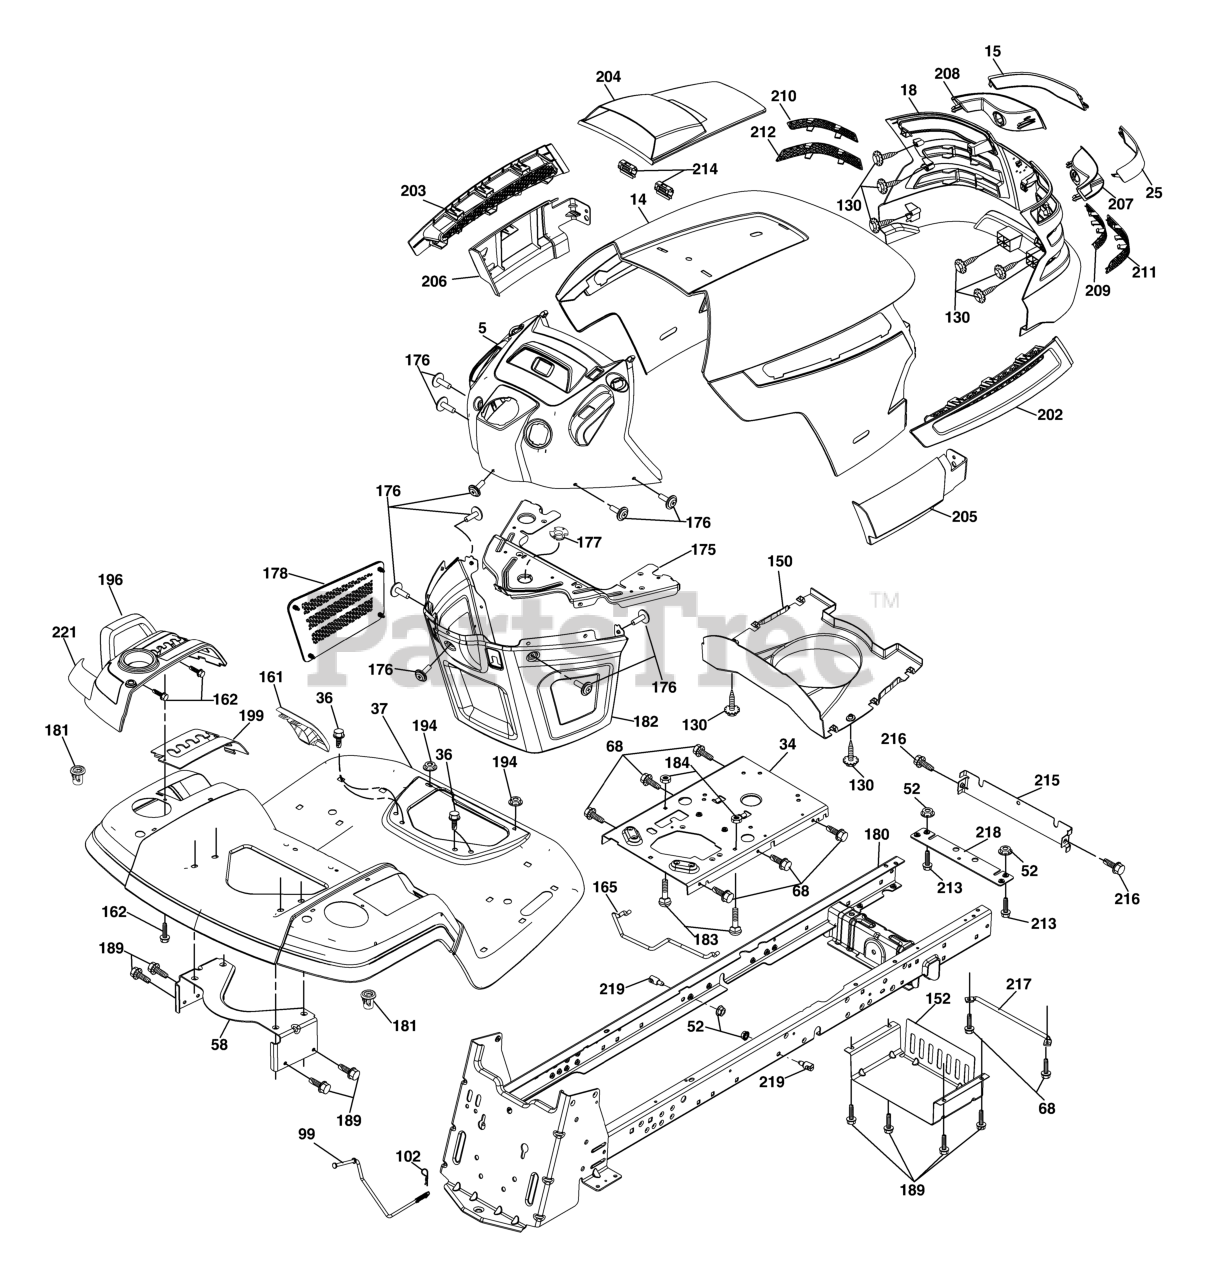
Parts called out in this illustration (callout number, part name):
5	DASH.HUSQ.UPR.ELE.SVMD
14	HOOD.PNT.HUSQVARNA.GT.
15	LENS.LH.TEX.GT.HUSQ.CL
18	GRILLE.ASM.TX.GT.HUSQ
25	LENS.RH.TEX.GT.HUSQ.CL
34	PLATE.ENGINE.WELDED.CHASSIS
36	SCREW 5/16"
37	FENDER.PNT.TX.GT.CH/FW.ORANGE
52	LOCKNUT
58	BRKT.SUPPORT.FNDR/TANK
68	Screw 5/16-18 x 1/2
99	ROD.BYPASS.K46.TG
102	RETAINER M
130	SCREW
150	AIR.DUCT.HOOD.TEX.GT.HUSQ
152	SHIELD.BROWNING.WTEXLT
156	SCREW
161	CONSOLE.FUEL.WINDOW.HU
162	SCREW.HI-LO.CONSOLE
165	SUPPORT.TANK.REAR.W/TEX
175	PLATE.CROSSMEMBER.HUSQ
176	RP SCREW.10-24X5/8.WSHD
177	BUSHING, STEERING
178	CARGO.ASM.NET.TXGT.W/C
180	CHASSIS.WLDMT.TX.GT.05
181	BUSHING.MNT.FEND.CRGO.
182	DASH.LOWER.COMMON.12V.
189	SCREW
194	NUT.71038.31-18.HEX.NYLOCK
196	RP CONSOLE.ASM.DECKLFT.W/
199	PLATE.DECK.LIFT.HUSQVARNA.GT
202	VENT.SIDE.HOOD.HUSQ.RH.GREY
203	VENT.SIDE.HOOD.HUSQ.LH.GRAY
204	VENT.TOP.HOOD.HUSQVARN
205	SKIRT.HOOD.SIDE.HUSQ.RH.GREY
206	SKIRT.HOOD.SIDE.HUSQ.LH.GREY
207	BEZEL.RH.TEX.GT.HUSQ
208	BEZEL.LH.TEX.GT.HUSQ
209	INSERT.HEX.GRILL.HUSQ.GREY
210	INSERT.HEX.GRILL.HUSQ.
211	INSERT.HEX.GRILL.HUSQ.
212	INSERT.HEX.GRILL.HUSQ.
213	BOLT
214	CLIP.RETAINER.TINNER.
215	COVER.CHASSIS.FRONT.WE
216	SCREW, 5/16-18 X 1/2
217	ROD PIVOT CHASSIS/HOOD
218	X-PIECE.HOOD.STOP.NON/
219	STUD.FASTNER.W/ANTI-ROTATE
220	LOCKNUT-FLANGE 5/16-18
221	REFLECTOR.LH.TEX GT HU
